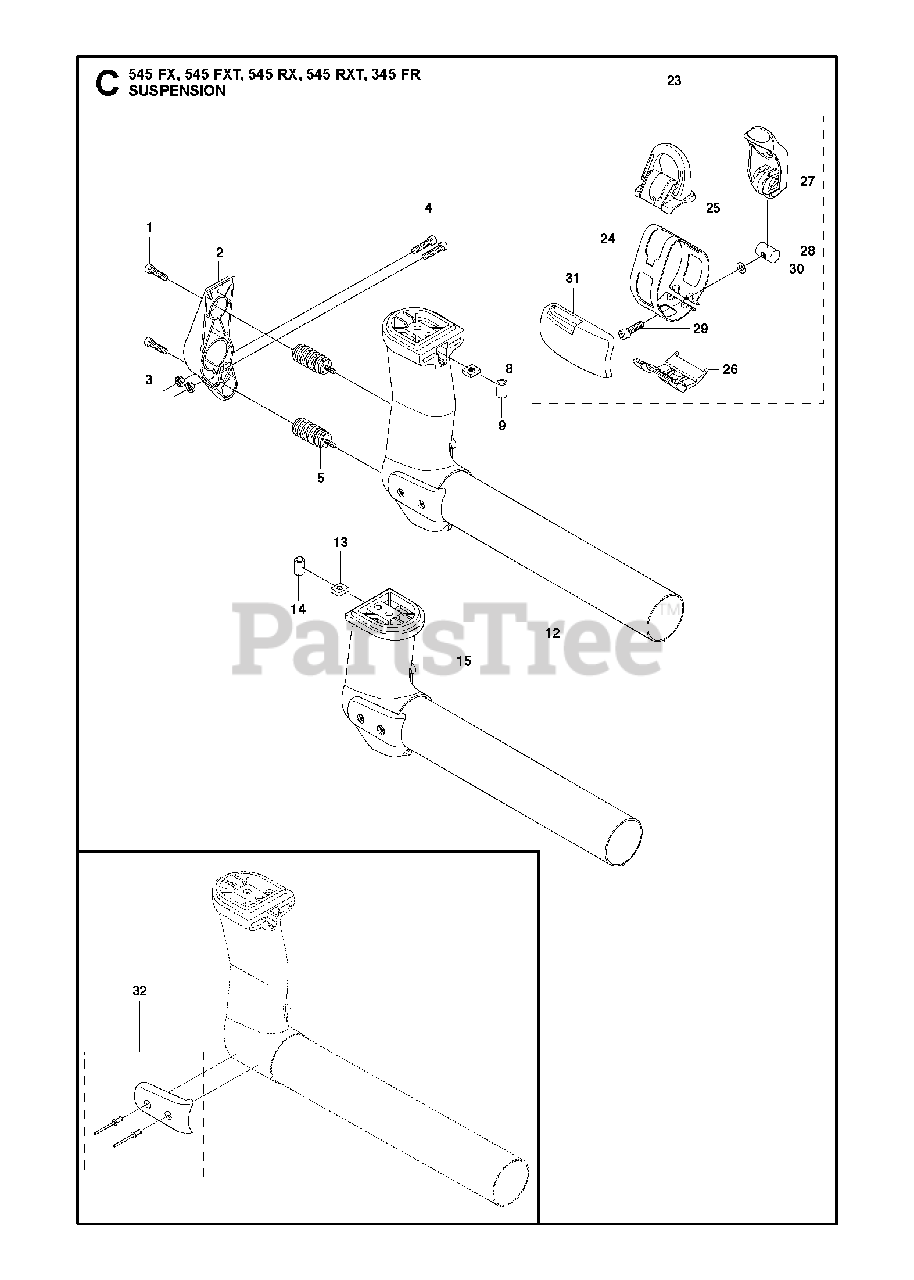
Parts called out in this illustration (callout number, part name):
2	HOLDER ANTIVIBRATION
12	SUSPENSION
15	SUSPENSION
24	BRACKET
25	LOOP
26	GUIDE RAIL
27	LEVER
28	NUT
29	SCREW
30	WASHER 5.3X12
31	WEAR PROTECTION
32	WEAR PROTECTION KIT
